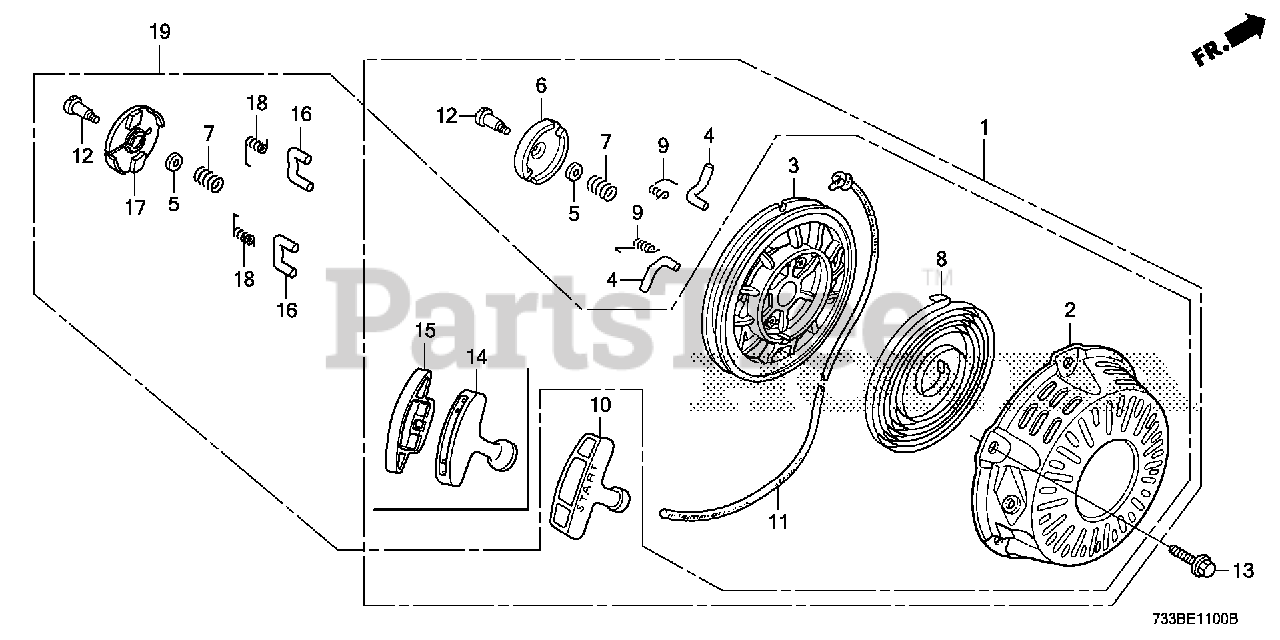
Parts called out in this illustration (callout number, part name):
1	STARTER ASSY., RECOIL *R280* (POWER RED)
2	CASE, RECOIL STARTER *R280* (Honda Code 7346836). (POWER RED)
3	REEL, RECOIL STARTER
3	REEL, RECOIL STARTER (BLACK)
4	RATCHET, STARTER
5	PLATE, FRICTION
6	GUIDE, RATCHET
7	SPRING, FRICTION
8	SPRING, RECOIL STARTER
9	SPRING, RETURN
10	KNOB, RECOIL STARTER
10	GRIP, STARTER
11	ROPE, RECOIL STARTER (#5X55")
12	SCREW, SETTING
13	BOLT, FLANGE (6X10)
